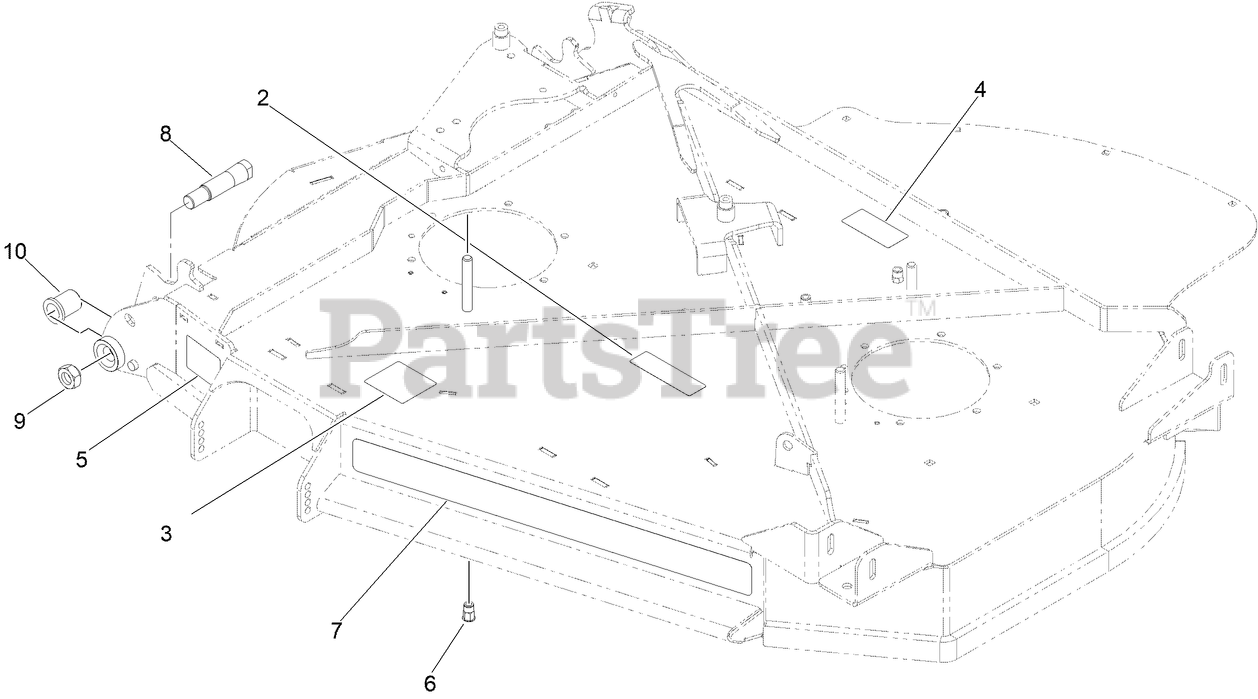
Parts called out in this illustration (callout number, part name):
2	DECAL-COVER, MISSING
3	DECAL-DANGER, THROWN OBJECT
4	DECAL-BOLT TORQUE
5	DECAL-WARNING, PINCH POINT
6	NUT-CLINCH,HEX
7	DECAL-144 INCH
8	BOLT-PIVOT PIN
9	NUT-LUG
10	BUSHING-FLANGED
